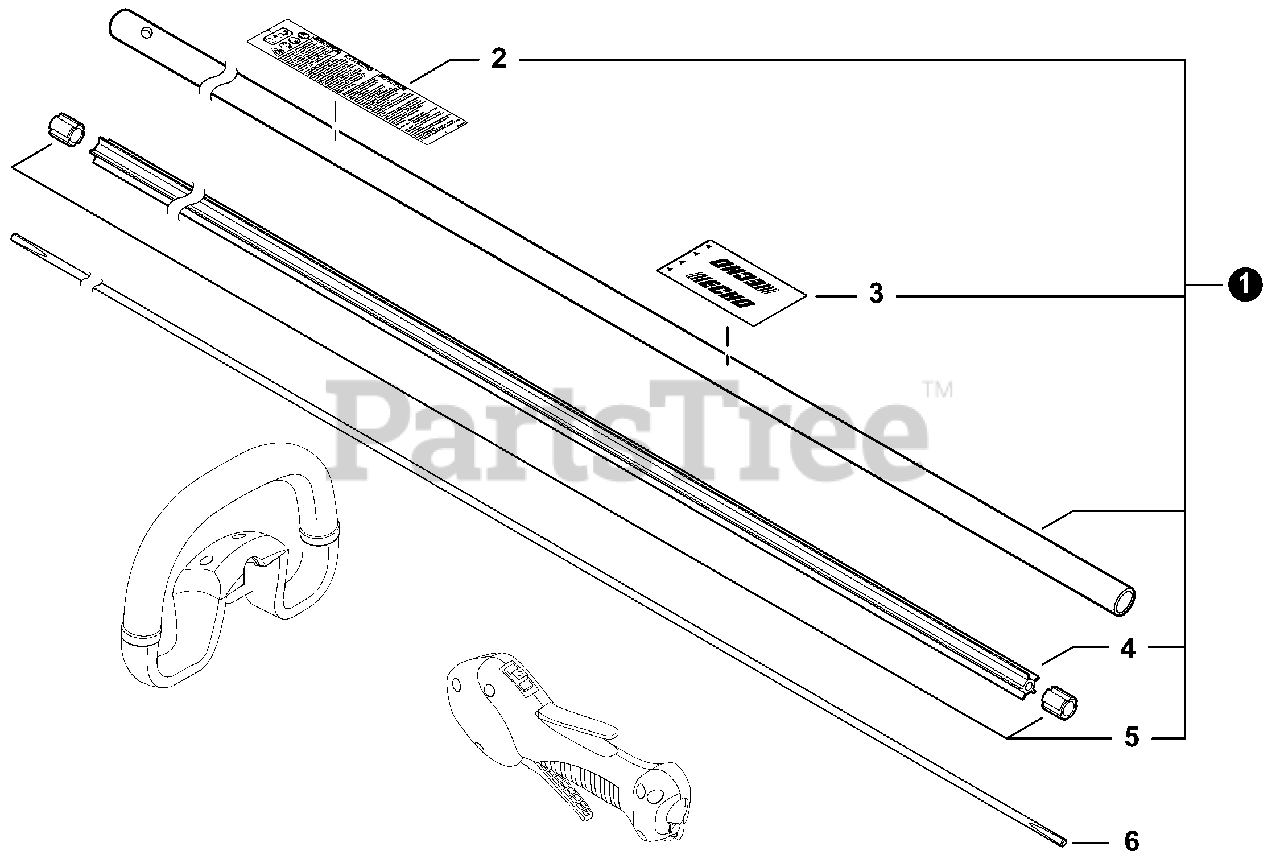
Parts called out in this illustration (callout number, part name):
1	MAIN PIPE ASSY
2	LABEL, CAUTION
3	LABEL, HANDLE LOCATION
4	LINER, FLEXIBLE 21.6×1420
6	DRIVESHAFT - FLEXIBLE
